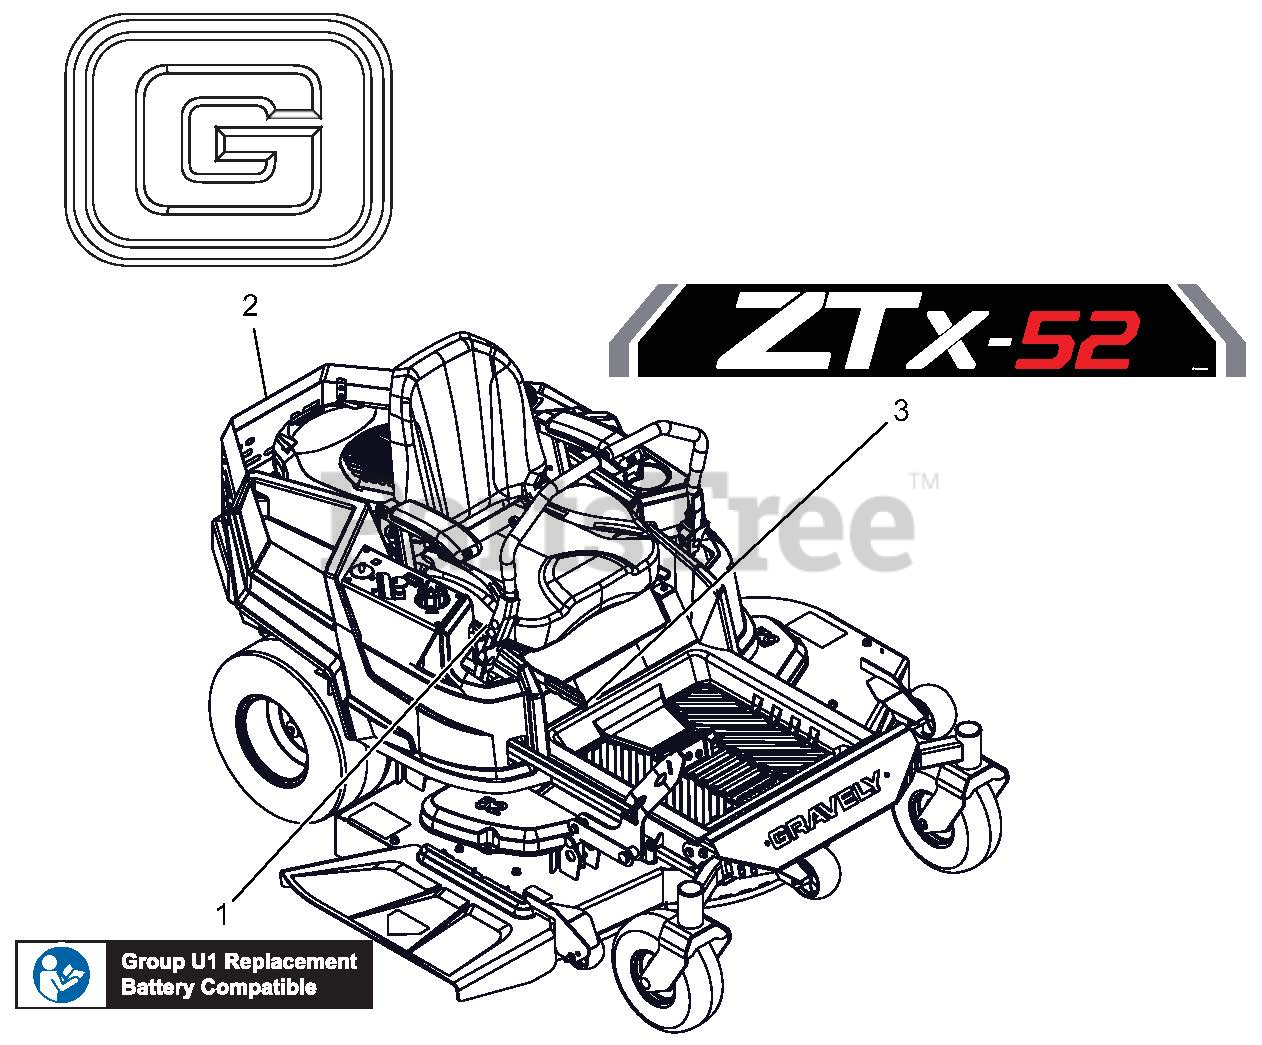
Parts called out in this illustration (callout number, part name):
1	DECAL, U1 REPLACEMENT BATTERY
2	DECAL, GRAVELY BRAND
3	DECAL, ZTX 52
